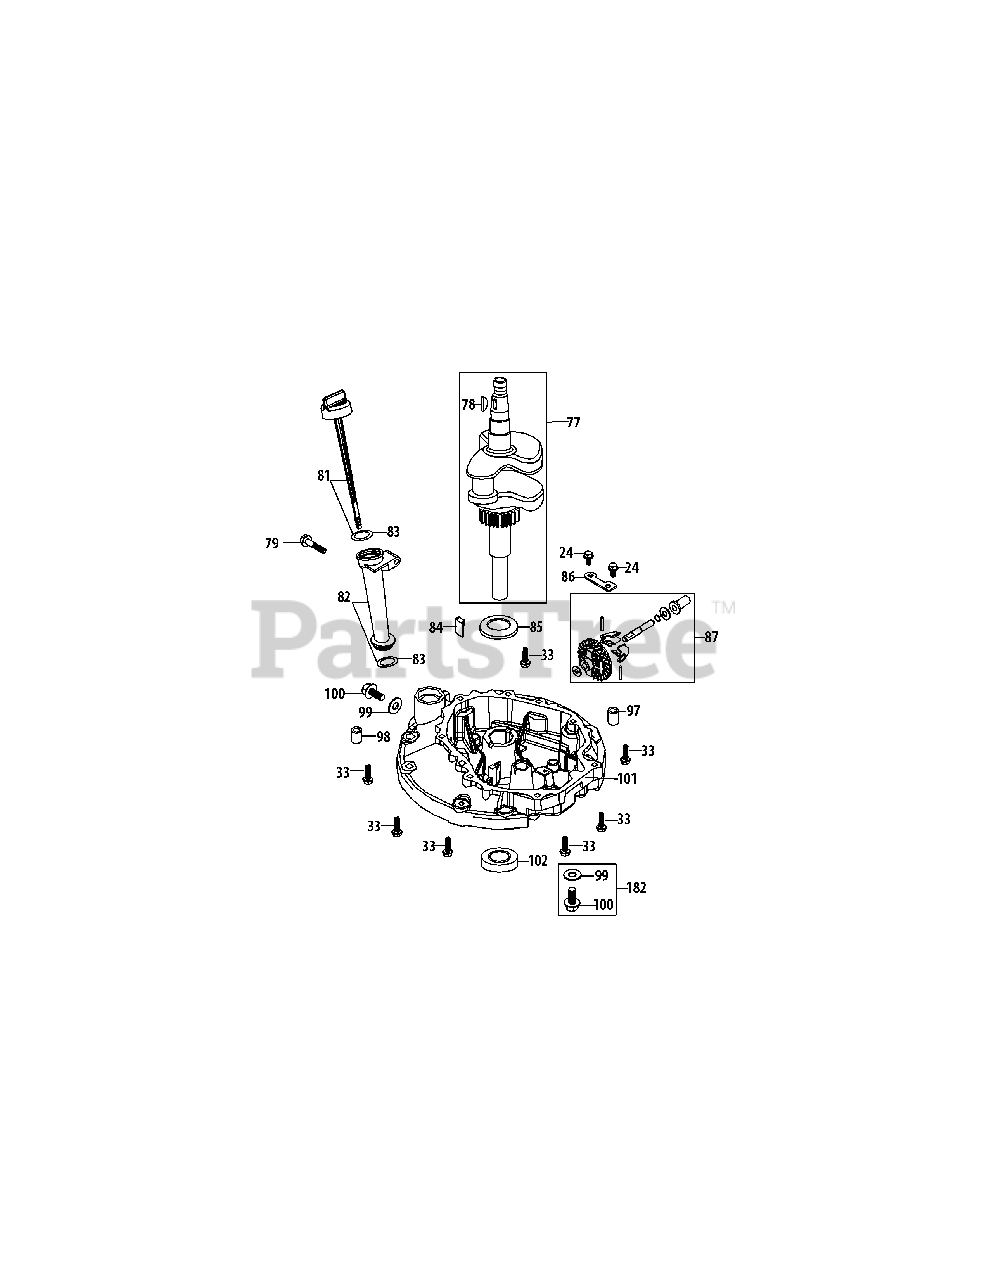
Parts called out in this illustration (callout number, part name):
24	Bolt M6×14
33	Bolt M6X28
77	Crankshaft Assembly
78	Woodruff Key
79	Dipstick/Af Bolt M6×35
81	Dipstick
82	Oil Fill Tube
83	Dipstick / Oil Fill Tube O-Ring
84	Oil Return Seal
85	Crankshaft Thrust Washer
86	Governor Gear Mounting Plate
87	Governor Gear/Shaft Assembly
97	Crankcase Cover Dowel 7X14
98	Crankcase Cover Dowel 9X14
99	Oil Drain Plug Washer
100	Oil Drain Plug
101	Crankcase Cover
102	Lower Crankshaft Seal
182	Oil Drain Plug & Washer Assy
